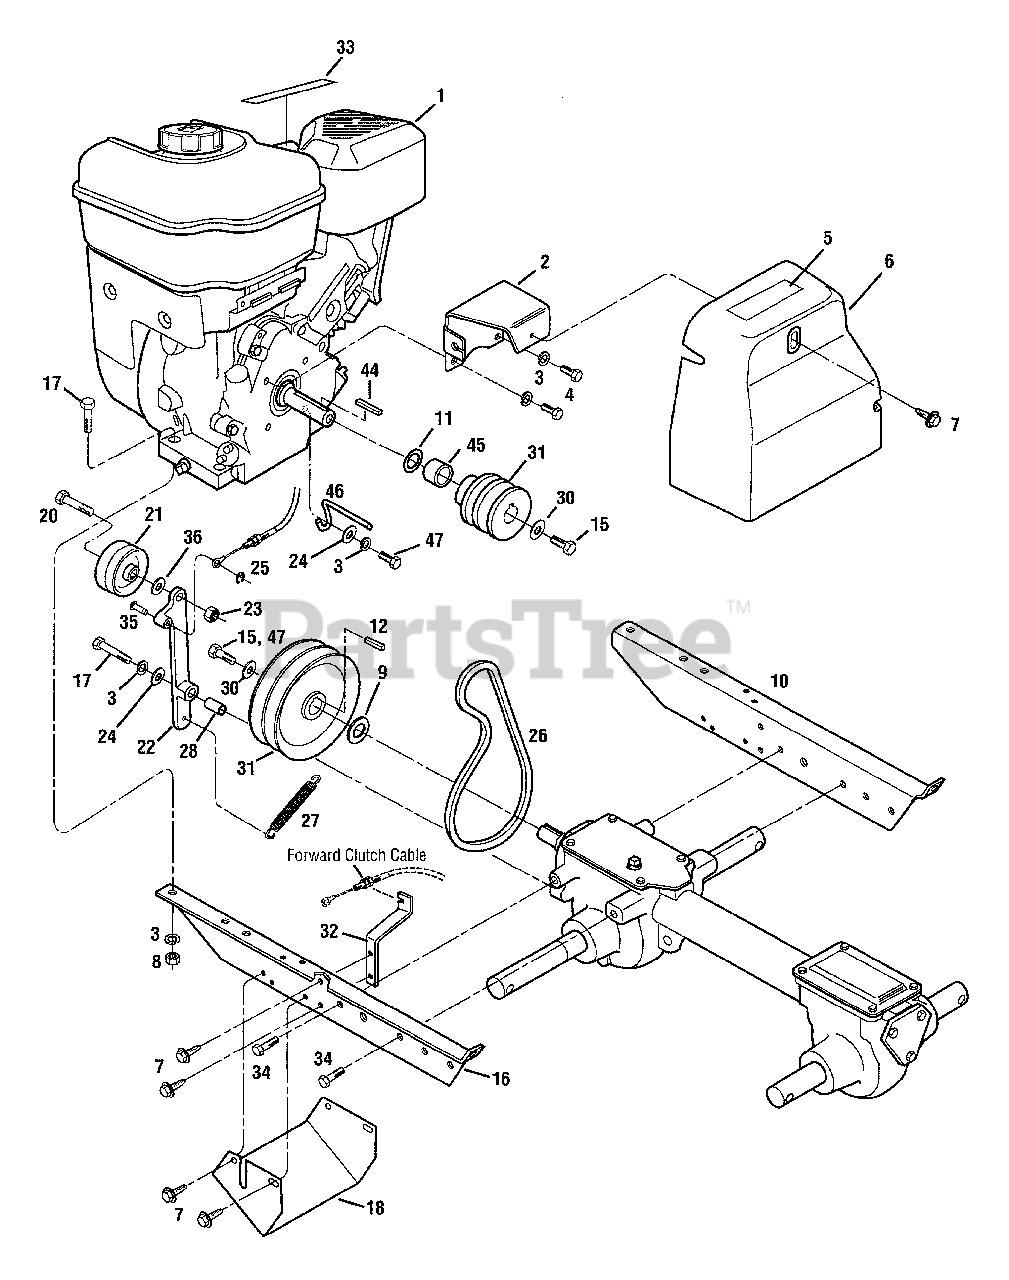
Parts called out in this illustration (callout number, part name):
1	Engine, Recoil Start
2	Bracket, Belt Cover
3	Lockwasher, 5/16
4	Hex Hd. Screw, 5/16-24 x 1/2
5	Decal, Hot Surfaces Warning
6	Belt Cover
7	Flange Screw, Self-Tapping, 1/4-20 x 1/2
8	Hex Nut, 5/16-18
9	Support Washer
10	Engine Bracket, Right
11	Shim
12	Key, 3/16" x 1"
15	Hex Screw, 5/16-24 x 1
16	Engine Bracket, Left
17	Hex Screw, 5/16-18 x 1-1/2
18	Guard, Belts/Pulleys
20	Hex Screw, 3/8-16 x 1-1/2
21	Forward Idler Pulley
22	Forward Idler Lever
23	Locknut, 3/8-16
24	Flat Washer
25	Klip Ring
26	Forward Drive Belt
27	Forward Return Spring
28	Bushing, Forward Idler Lever
30	Belleville Washer
31	Transmission Pulley
32	Bracket, Cable Mounting
33	Decal, Stabilization
34	Hex Screw, 5/16-18 x 5/8
35	Clevis Pin
36	Flat Washer, 3/8
44	Key, 3/16 x 1-1/2
45	Spacer
46	Forward Belt Guide
47	Hex Hd. Screw, 5/16-24 x 3/4
